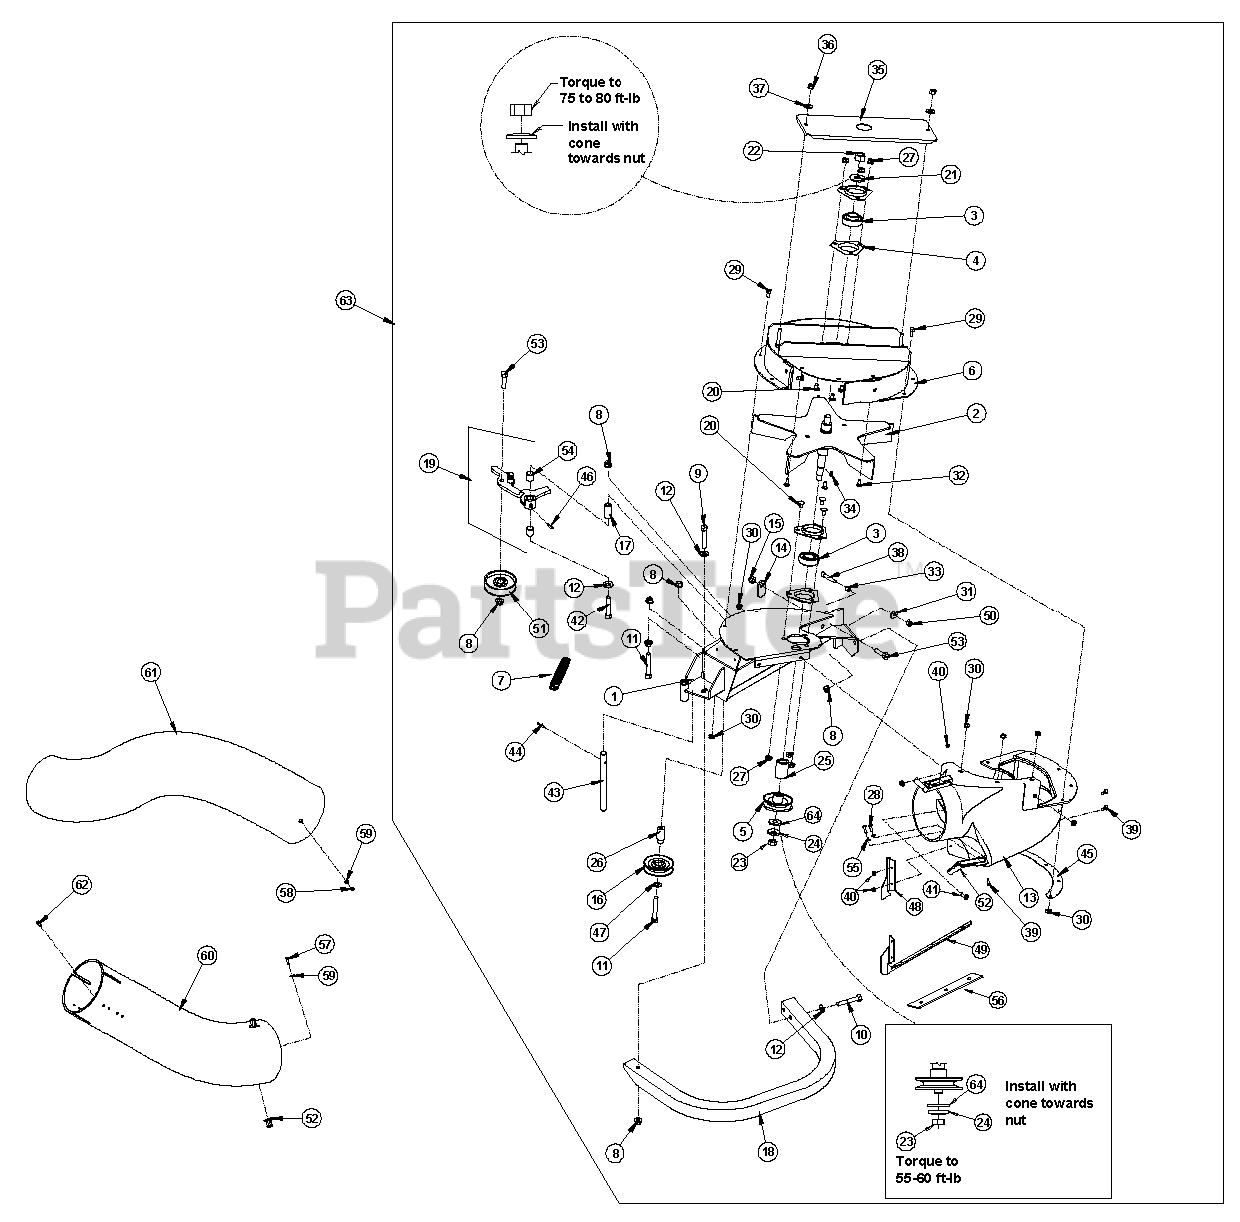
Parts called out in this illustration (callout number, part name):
1	WLD,BLOWER MOUNT
2	IMPELLER
3	BEARING
4	HOUSING-FLANGE
5	SHEAVE-BLOWER
6	ASM, UPPER HOUSING LZUV52
7	SPRING-IDLER
8	NUT-HHF, WHIZ
9	SCREW-HH
10	SCREW-HH
11	BOLT-CARR
12	WASHER-FLAT
13	CHUTE-BLOWER, SMALL
14	LATCH-CATCHER, GRASS
15	NUT-LOCK, NI
16	IDLER-INSIDE
17	BUSHING-PIVOT, IDLER
19	ASM, IDLER ARM - SERVICE
20	SCREW-CARR
21	WASHER-SPRING
22	NUT-HEX
23	NUT-JAM
24	WASHER-SPRING
28	SCREW-PPH
29	SCREW-HH
31	WASHER-SPRING
32	SCREW-CARR
33	BUSHING, LOCATOR
34	KEY-WOODRUFF
35	ASM, BEARING COVER
36	NUT-LOCK, NI
37	WASHER-FLAT
38	SCREW-HSH
39	SCREW-HEAD, TRUSS
42	SCREW-HSBH
43	SHAFT-CATCHER, GRASS
44	PIN-ROLL
45	PLATE-BACKING, BLOWER
46	FITTING-GREASE
47	WASHER-FLAT
48	PLATE, FILLER
49	PLATE, BLOCKER
50	NUT-HEX
51	IDLER-FLAT
52	LATCH DRAW
53	SCREW-HH
54	BUSHING
55	WASHER-FLAT
56	PLATE-REINFORCEMENT
57	SCREW-PPH
58	NUT-LOCK, NI
59	WASHER-FLAT
60	KIT,LOWER TUBE
61	TUBE-UPPER
62	SCREW-HWH
63	ASM, BLOWER LZUV52 - SERV
64	WASHER-SPACER
